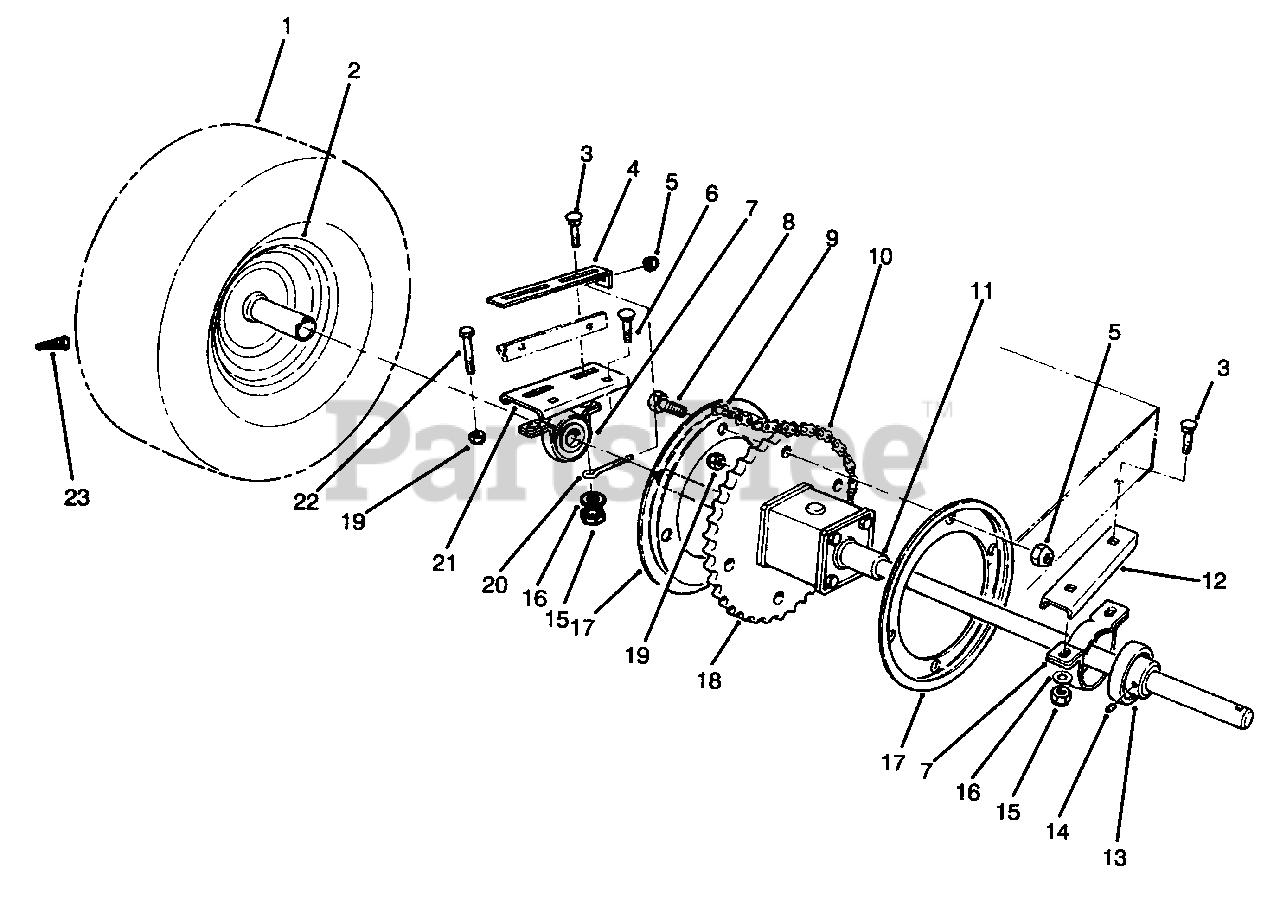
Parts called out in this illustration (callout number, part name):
3	Bolt-Carriage
4	Plate-Adjusting
5	Nut-Lock
6	Bolt-Carriage
7	Mount-Bearing
8	Screw-Cap Hex. Hd.
9	Link-Connecting
10	Chain (Incl. Ref. #9)
11	Differential
12	Support L.H.
13	Bearing (Incl. Ref. #14)
14	Screw-Set
15	Nut-Lock
16	Washer-Flat
17	Guide-Chain
18	Sprocket
19	Nut-Lock
20	Screw-Adjusting
21	Support R.H.
22	Bolt-Axle
23	Valve Stem w/Cap
